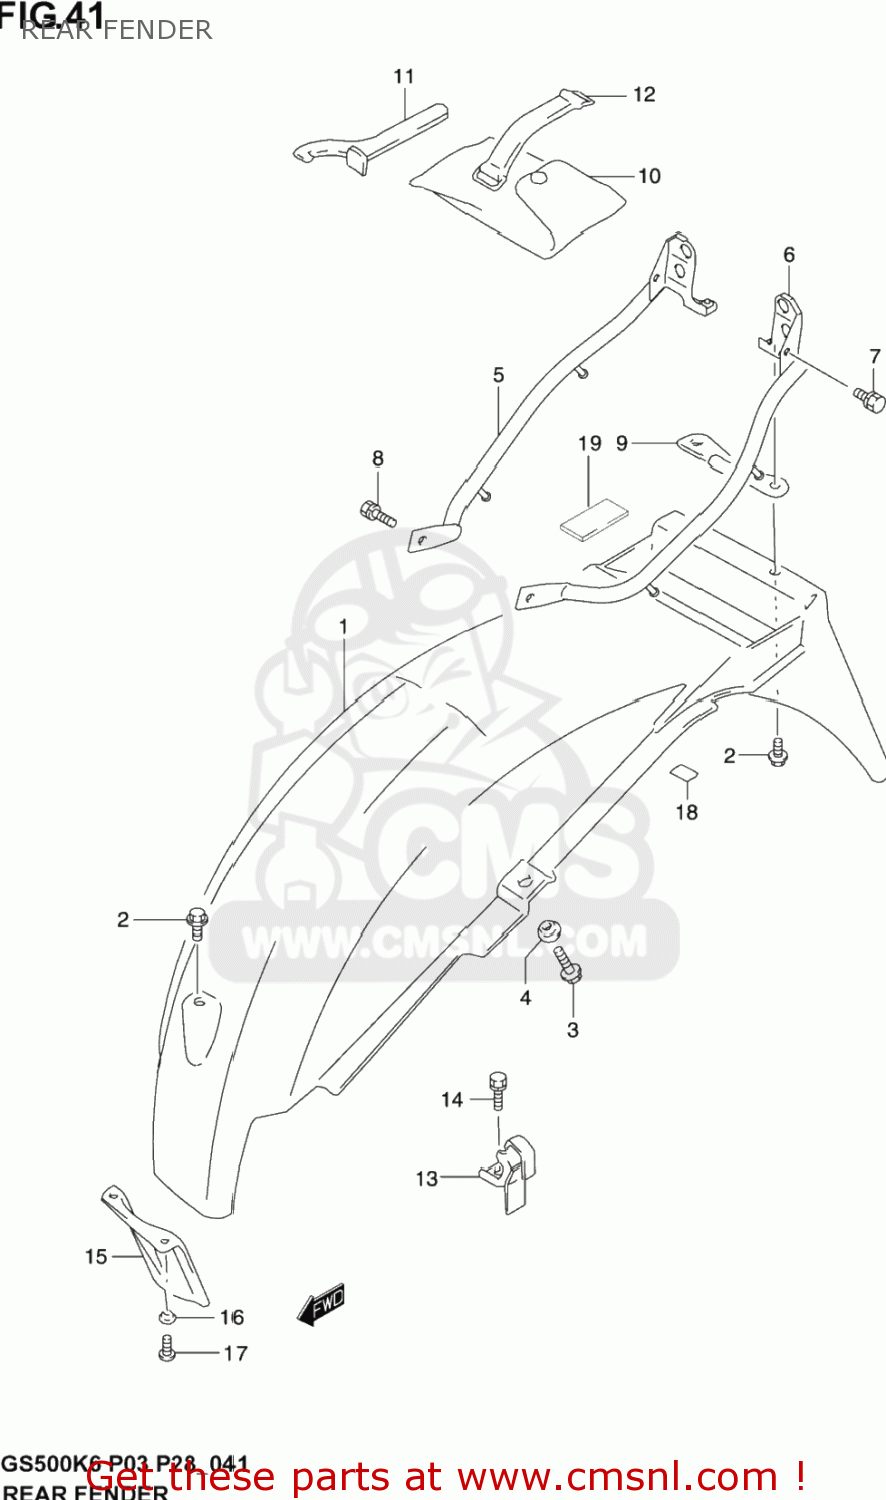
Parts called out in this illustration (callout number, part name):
1	BODY,REAR FEND
2	BOLT(6X16)
3	BOLT
4	WASHER
5	BRACE,RR FENDER,R
6	BRACE,RR FENDER,L
7	BOLT
8	BOLT
9	PLATE,TOOL HOLDER
10	TOOL ASSY
11	CLAMP, WRENCH
12	O RING(D:3.53,ID:69.44)
13	HOLDER,HELMET
14	BOLT
15	MUD GUARD, REAR UNIT
16	WASHER
17	SCREW
18	TAPE, REAR FENDER
19	PROTECTOR(20X50X11)
